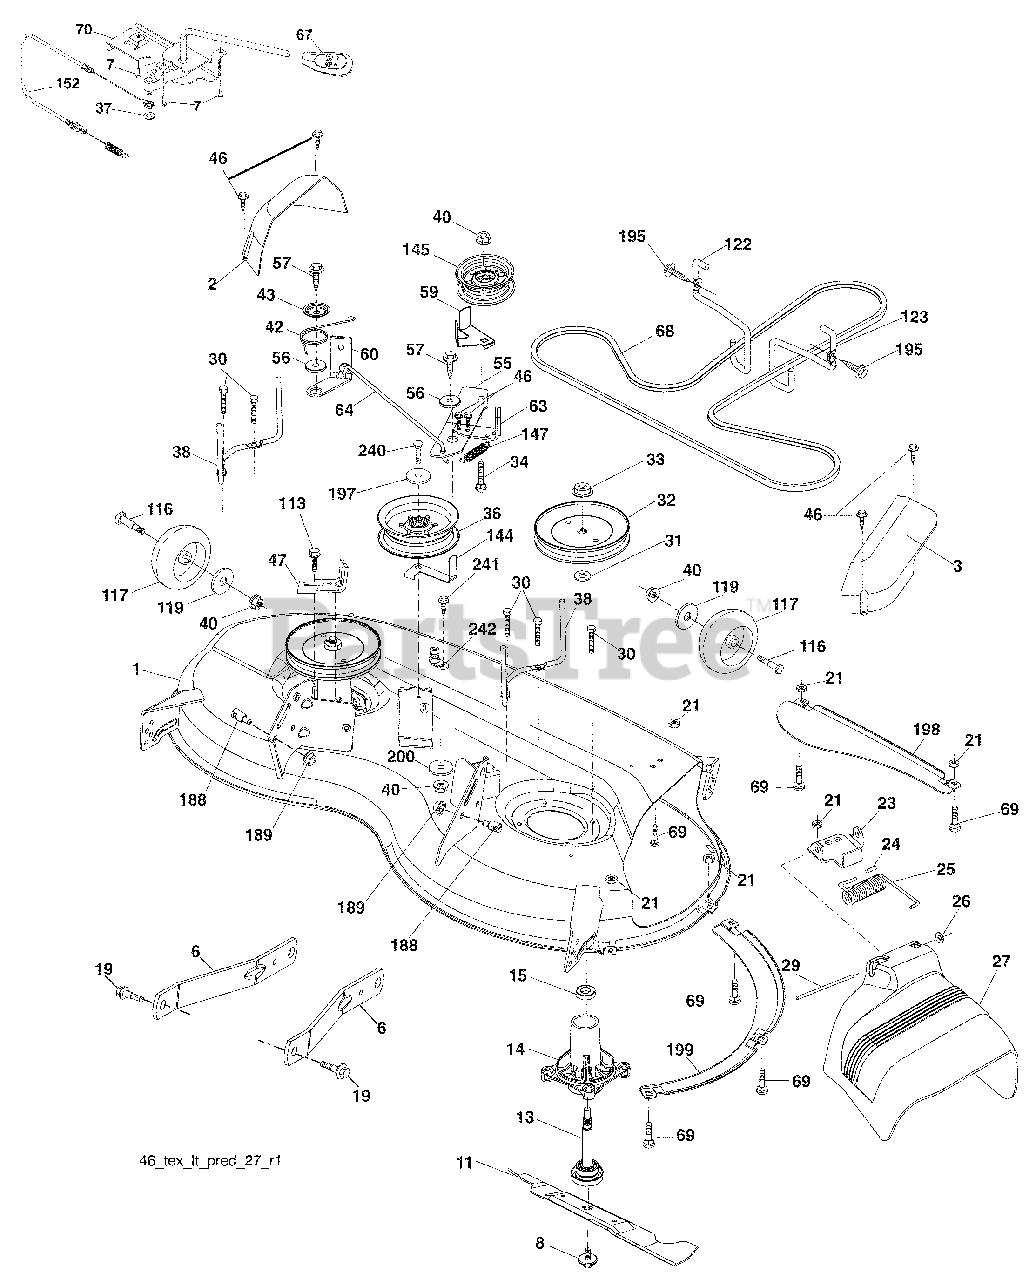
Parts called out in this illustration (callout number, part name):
1	Mower Housing
2	Cover Mandrel RH
3	Cover Mandrel LH
6	Arm Suspension
7	Screw # 10 x 0.750
8	Bolt/Washer asm 7/16-20 unf
11	Blade Mower Hi Lift
13	Shaft Assembly, Mandrel
14	Housing, Mandrel
15	Bearing, Ball, Mandrel
19	Bolt, Shoulder
21	Nut
23	Bracket, Deflector
24	Cap, Sleeve
25	Spring, Torsion, Deflector
27	Shield, Deflector
29	Rod, Hinge
30	Screw Thdrol Rolling Wsh Hd
31	Washer, Spacer
32	Pulley, Mandrel
33	Nut, Toplock, Flanged
34	Bolt Carr Sh. 3/8-16 x 1-1/2 Gr. 5
36	Pulley, Idler, Flat
37	Washer 13/32 x 13/16 x 16 Ga.
38	Keeper Belt LH Mandrel
40	Nut, Lock Flg. 3/8-16 unc
42	Spring Torsion Brake
43	Spring Torsion Retainer
47	Bracket Clutch Cable
55	Arm, Idler
56	Spacer, Retainer
57	Screw Hexwsh Thd 3/8-16 x 1
59	Guard, Tuv Idler (94)
60	Arm Brake Mower LH
63	Arm Brake Mower
64	Linkage Brake
67	Handle, Clutch Cable
68	V-Belt
69	Bolt
70	Clutch Asm. Cable
113	Screw 5/16-18
116	Bolt, Shoulder
117	Wheel, Gauge
119	Washer 13/32 x 1-1/4 x 12 Ga.
122	Keeper Belt Eng. LH
123	Keeper Belt Eng. RH
144	Keeper Belt
145	Pulley Idler
147	Spring Return
152	Cable Clutch Manual w/Spr.
188	Stud Fastener
189	Nut Lock Hex Flange
195	Screw 3/8-16 x 3/4
197	Washer 13/32 x 13/16 x 12 Ga.
198	Baffle Center Front
199	Baffle Front RH
200	Washer 13/32 x 1 x 1/2 11 Ga.
240	Bolt 3/8-16 unc x 2-1/4 Gr. 5
242	Washout Port
